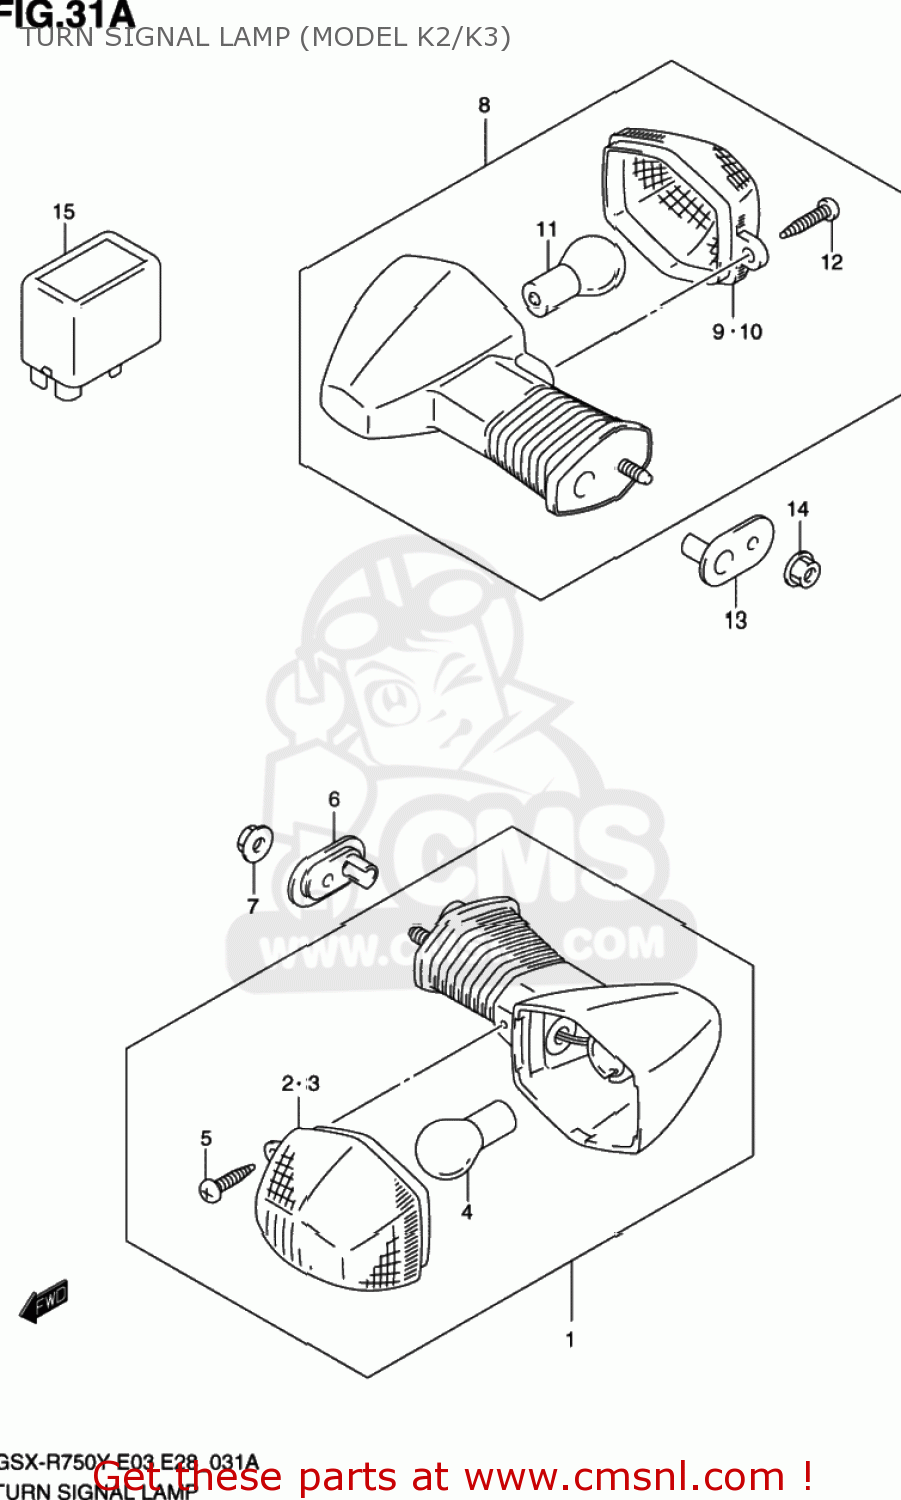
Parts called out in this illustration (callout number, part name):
1	LAMP ASSY,FR TURN SIGNAL,R
2	LENS
3	LENS
4	BULB(12V21W)
5	SCREW
6	PLATE,TURNSIGNAL LAMP
7	NUT
8	LAMP ASSY,RR TURNSIGNAL,R
9	LENS
10	LENS
11	BULB(12V21W)
12	SCREW
13	PLATE,TURNSIGNAL LAMP
14	NUT
15	RELAY ASSY,TURNSIGNAL LAMP
